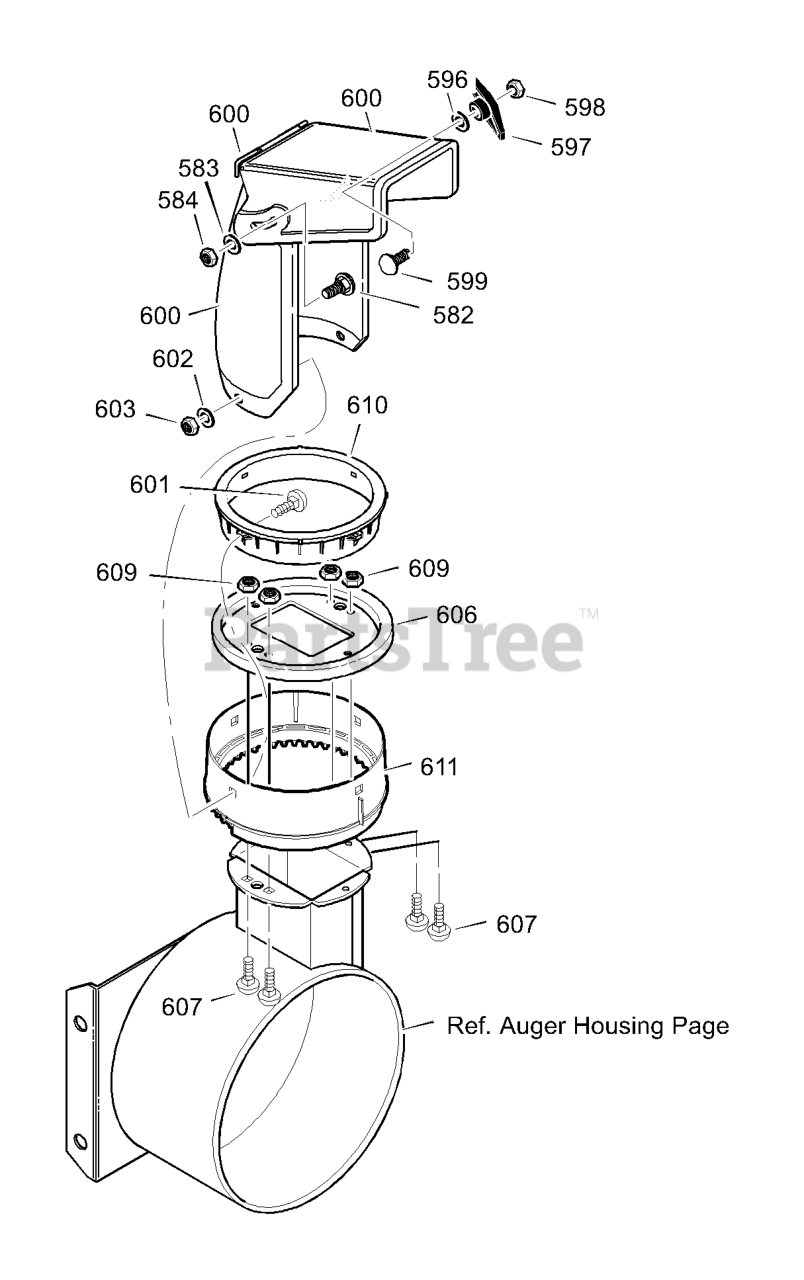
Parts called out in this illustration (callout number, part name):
582	SCREW, 5/16-18 x 1.00
583	WASHER, FLAT
584	NUT, 5/16-18
596	WASHER
597	KNOB, T 3.00
598	NUT, 5/16-18
599	BOLT, 5/16-18X1..00
600	CHUTE ASSEMBLY
601	BOLT, 5/16-18
602	WASHER, FLAT
603	NUT, 5/16-18
606	CHUTE COLLAR
607	SCREW, 1/4-20 X 0.75
609	NUT, 1/4-20 HEX NYLOCK
610	RETAINER RING INNER
611	RETAINER RING OUTER
